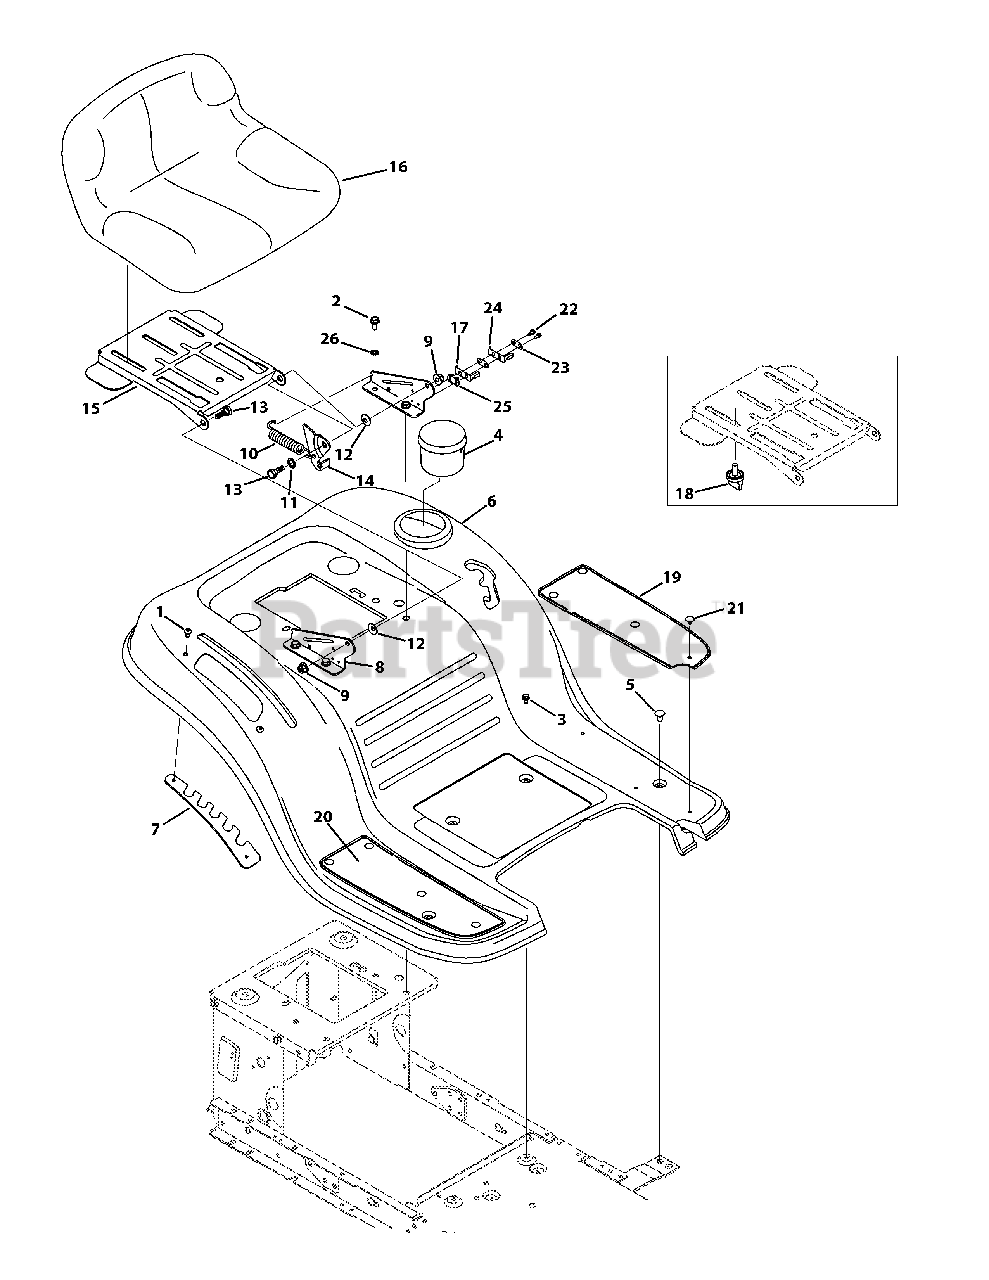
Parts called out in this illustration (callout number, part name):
1	Screw, 1/4-20 x .500
2	Screw, 5/16-18 x .750
3	Screw Pan Torx Head, 1/4-20 x .500
5	Screw Carriage, 1/4-20 x .62
6	Fender - Red
7	Lift Adjuster Bracket - Powder Black
8	Seat Mount Bracket - Powder Black
9	Flangelock Nut, 5/16-18
10	Extension Spring
11	Flat Washer, .510x .750 x .033
12	Bell Washer, .340 x .872 x .060
13	Shoulder Screw, 5/16-18 x .437 x .268
14	Lift Seat Bracket
15	Pivot Seat Manual Adjust Bracket
16	Med. Back Seat, Black
17	Inner Seat Spring
18	Knob, 3/8-16 x .875
19	Foot Pad, LH
20	Foot Pad, RH
21	Ratchet Clip, .250 x .500
22	Screw, 8-18 x .500
23	Insulator Plate
24	Outer Seat SPring
25	Insulator Boss Plate
26	Loack Washer, 5/16
